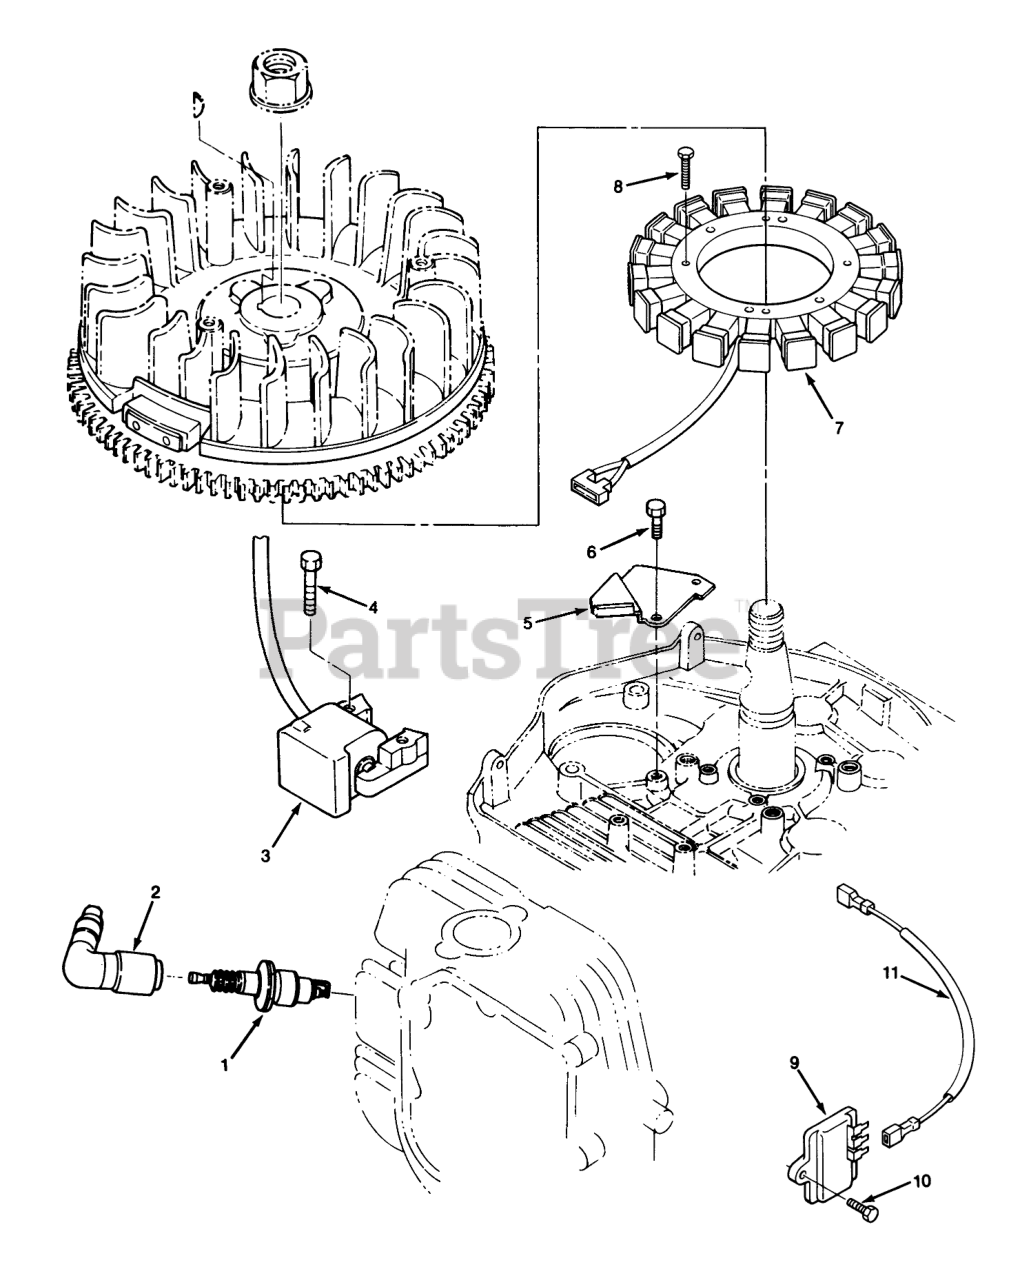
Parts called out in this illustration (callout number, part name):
1	Plug-Spark
3	COIL-IGNITION
4	HHSTB-M6 X 27MM
5	CLAMP-CORD
6	HHSTB-M6 X 14MM
7	STATOR
8	SCREW
9	Regulator
10	HHSTB-M6 X 14MM
11	HARNESS
